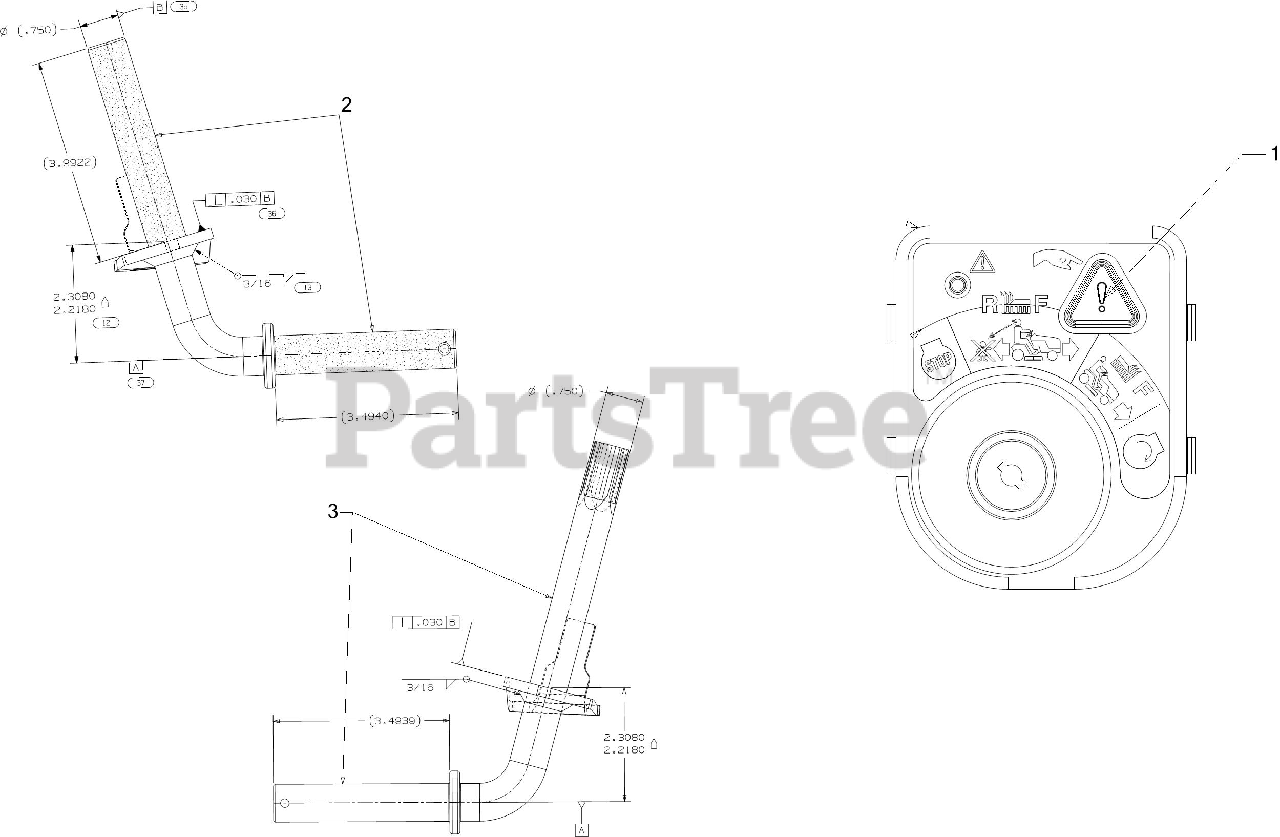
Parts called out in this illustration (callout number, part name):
1	IGNITION MODULE SWITCH RMC (MAN PTO BLK)
2	FRONT AXLE ASSEMBLY (LH)
3	FRONT AXLE ASSEMBLY (RH)
